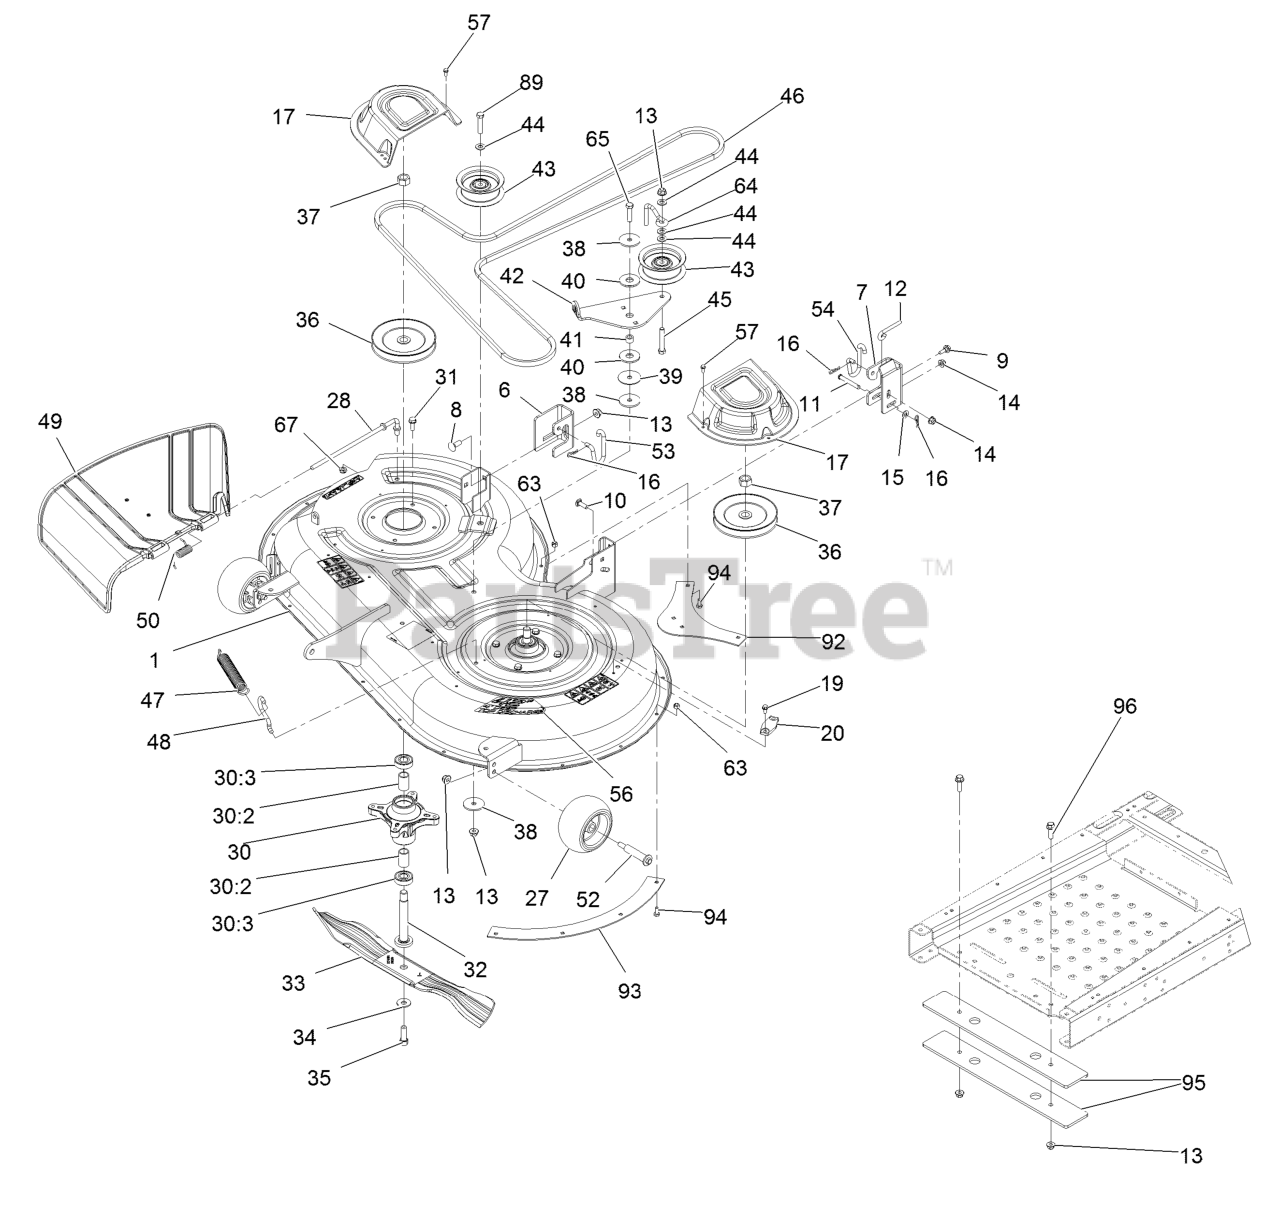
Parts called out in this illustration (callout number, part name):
1	42 Inch Deck And Decal ASM
6	Bracket-Hanger, RH
7	Bracket-Hanger, LH
8	Bolt-Carriage 3/8-16 X 1
9	Screw-HH Flg 1/4-20 X 3/4 Tf
10	Bolt-Carriage 5/16-18 X 1 Sp
11	Pin-Clevis
12	Rod-Level, Deck
13	Nut-Nyloc 3/8-16 Flg
14	Nut-Nyloc 5/16-18 Flg
15	Washer-5/16 SAE
16	Hairpin-Cotter
17	Cover-Belt
19	Screw-HWH 1/4-20 X 1/2 Taptite
20	Cover-Washout Port
27	Roller-Scalp, Anti
28	Rod-Pivot
30	Spindle ASM
30:3	Bearing-Ball
31	Screw-HWH 3/8-16 X 7/8 Taptite
32	Shaft-Spindle
33	Blade-21.6 In
34	Washer-Spring Disc
35	Screw-HH 7/16-20 X 1.36 Gr8
36	Pulley
37	Nut-Hex 5/8-18
38	Washer-Rebound
40	Washer-Friction, Composite
42	Arm-Idler
43	Pulley-Idler, Flat
44	Washer-3/8 SAE
45	Screw-HH 3/8-16 X 2 1/4
46	V-Belt
47	Spring-Extension
48	Hook-Return, Spring
49	Deflector
50	Spring-Torsion
52	Bolt-HH Shoulder 3/8-16 X 3.79
53	Link-Retention, Deck (RH)
54	Link-Retention, Deck (LH)
57	Screw-HWH #10-24 X 1/2 Taptite
63	Nut-Nyloc 1/4-20
64	Guide-Idler, Belt
65	Screw-HH 3/8-16 X 1 1/2
67	Nut-Nyloc 3/8-16 Thin
89	Screw-HH 3/8-16 X 1 3/4
92	Baffle-Blowout, Rear
93	Baffle-Blowout, Side
94	Screw-HH 1/4-20 X 5/8
95	Plate-Weight
96	Screw-HHF
